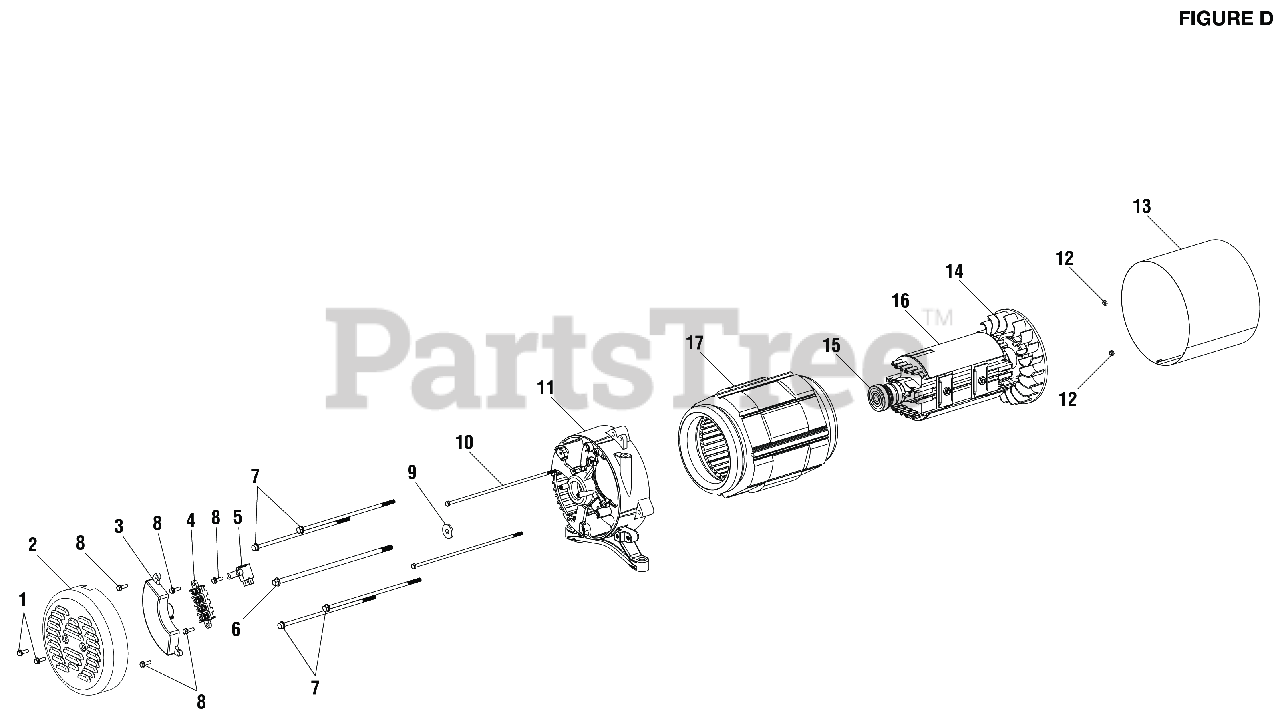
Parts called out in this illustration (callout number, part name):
1	Bolt (M5 x 12 mm, Hex Flange Hd.)
2	Brush Cover
3	Automatic Voltage Regulator (5000 Watt)
4	Terminal Block
5	Brush Assembly 190 mm
6	Rotor Bolt (170 mm)
7	Bolt (M5 x 170 mm, Hex Washer Hd.)
8	Bolt (M5 x 16 mm, Hex Flange Hd.)
9	Washer (ID10.5 x OD25 x 2t)
10	Bolt (M5 x 170 mm, Hex Washer Hd.)
11	Bearing Housing'
12	Hex Nut (M5)
13	Generator Head Cover
14	Fan (190 mm)
15	Ball Bearing (190 mm)
16	ROTOR, RD907500P, SHENFA, AL, CLASS H
17	STATOR, RD907500P, SHENFA, AL, CLASS F
